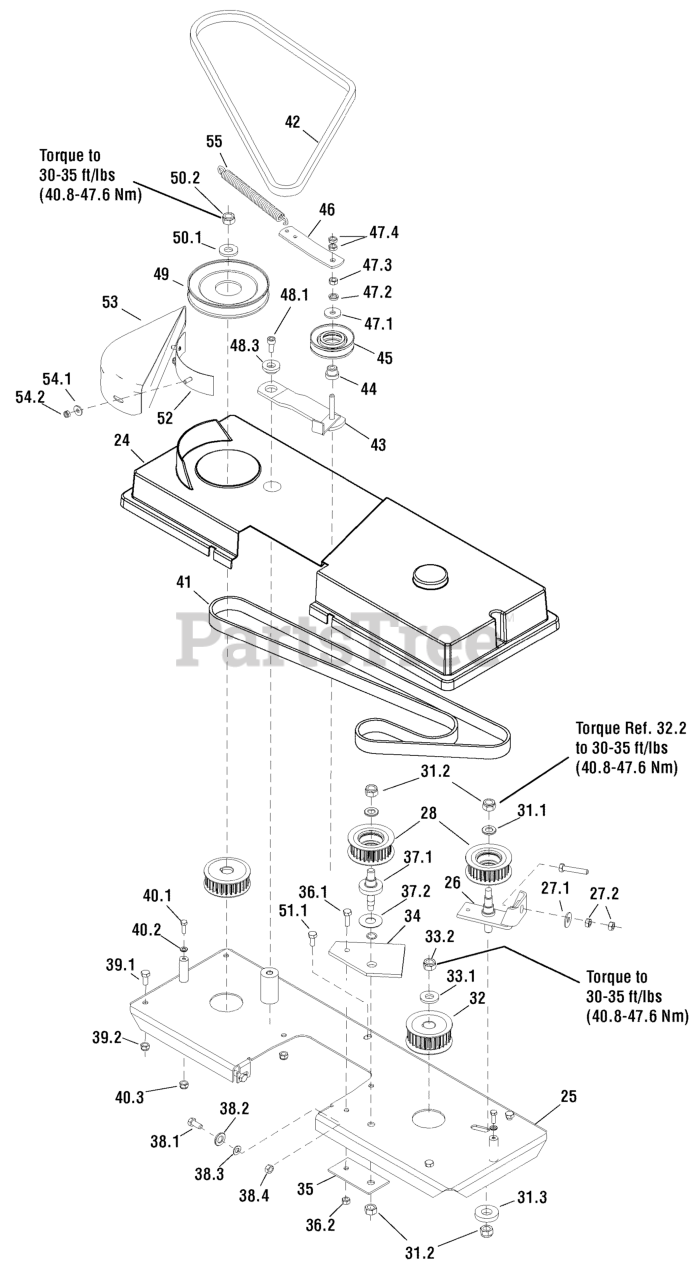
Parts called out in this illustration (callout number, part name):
24	COVER, Plastic 0-8547-369
25	MAIN BOARD
26	FOOTING, Complete
27.1	WASHER, Zinc, 9
28	PULLEY, Belt 28 Z
31.1	WASHER, 13
31.2	NUT, M12
32	PULLEY, Belt
33.1	WASHER, 0-9220-727
33.2	NUT, M12
34	REINFORCEMENT
35	REINFORCEMENT
36.1	SCREW, M8 x 25
36.2	NUT, Flange Lock, M8
38.1	SCREW, Zinc M8 x 20
38.2	WASHER, 13
38.3	WASHER, 8.4
38.4	NUT, M8
38.4	NUT, Flange Lock, M8
39.1	SCREW, M8 x 40
39.2	NUT, Flange Lock, M8
40.1	SCREW, M6 x 16
40.2	WASHER, Zinc, 6.6
40.3	NUT, Flange Lock, M6
41	BELT, Two Side Tooth K+K20DS 1760
42	V-BELT, Li, 17 x 1200
43	HOLDER, Complete
44	STUD, 0-9321-263
45	ROLLER, W 3500-3712
47.1	WASHER, Zinc, 9
47.2	WASHER, 8
48.1	SCREW, M8 x 20 10.9 ZN DIN 912
48.3	WASHER, 0-9221-222
49	PULLEY, Belt 9-3325-234, Complete
50.1	WASHER, 0-9220-727
50.2	NUT, M12
51.1	SCREW, M8 x 25
52	REINFORCEMENT
53	COVER, Pulley, Belt 0-8534-203
54.1	WASHER, Zinc, 6.6
55	SPRING, 0-9746-460
